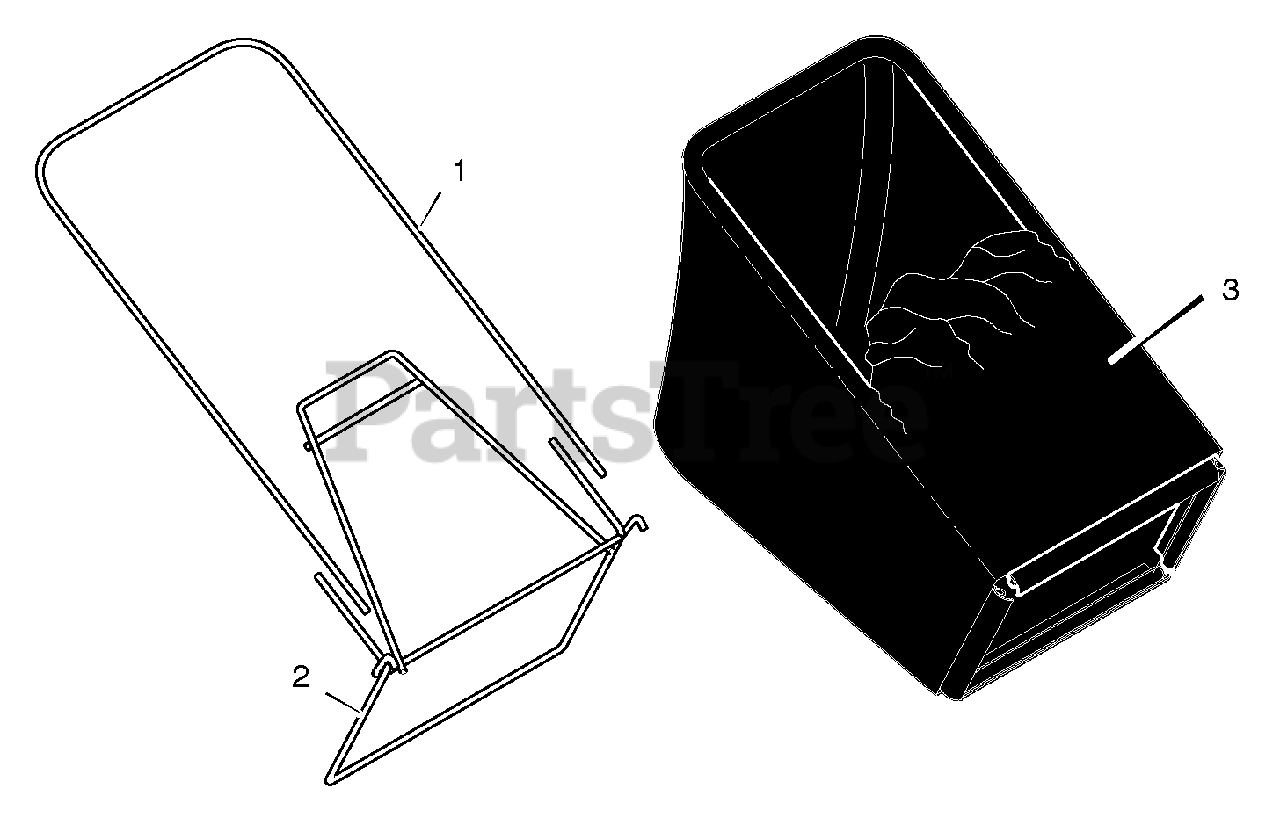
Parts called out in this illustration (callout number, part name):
1	Tube, Bag
2	Frame Assembly
3	Bag, Cloth - Black
